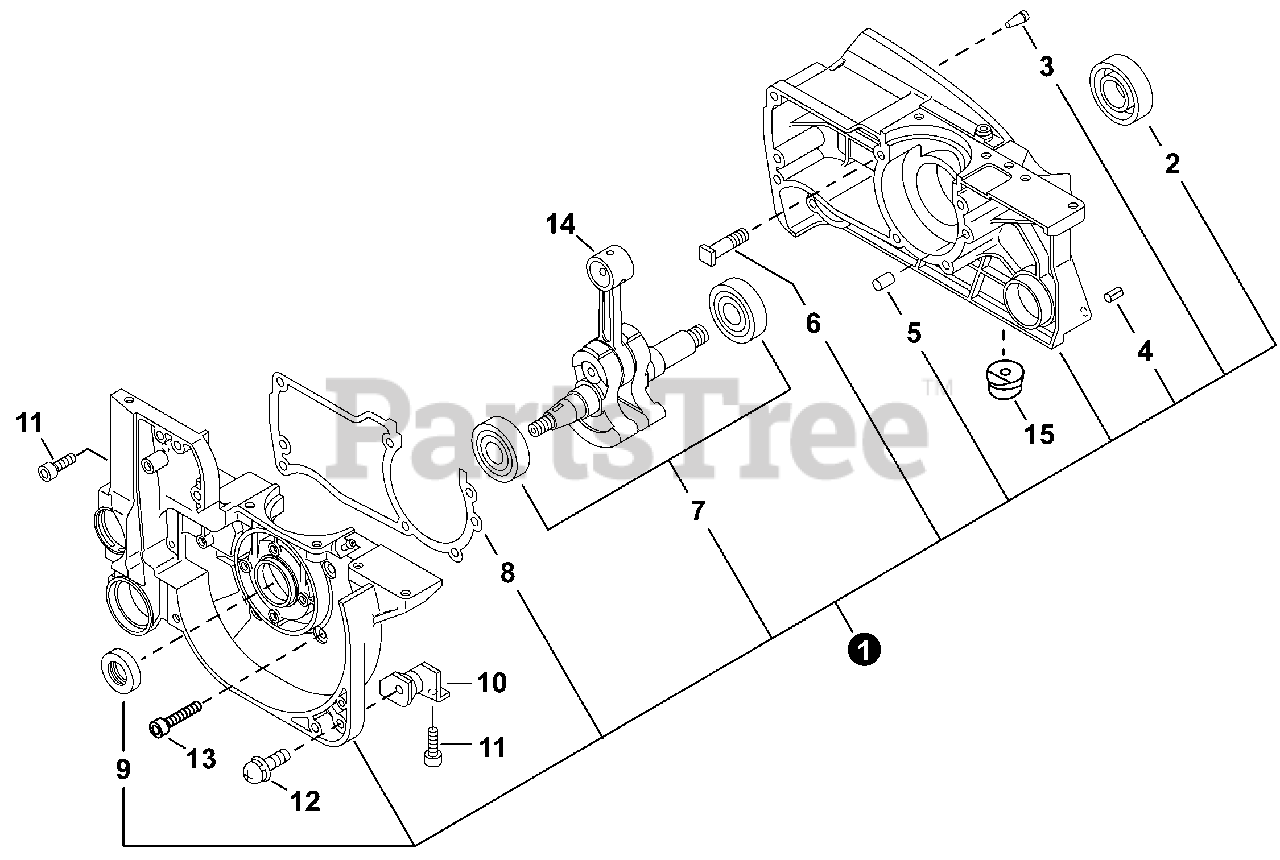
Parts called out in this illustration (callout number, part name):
1	CRANKCASE KIT - GRAY
1	CRANKCASE KIT - ORANGE
2	SEAL, OIL
3	VENT ASSY
4	PIN, SPRING 5x10
5	PIN, LOCATING 5x10
6	STUD, GUIDE BAR 8
7	BEARING, BALL 6203 C3
8	GASKET, CRANKCASE
9	SEAL, OIL
11	BOLT 5x20
12	SCREW 5x14
13	BOLT M5x35
14	CRANKSHAFT
